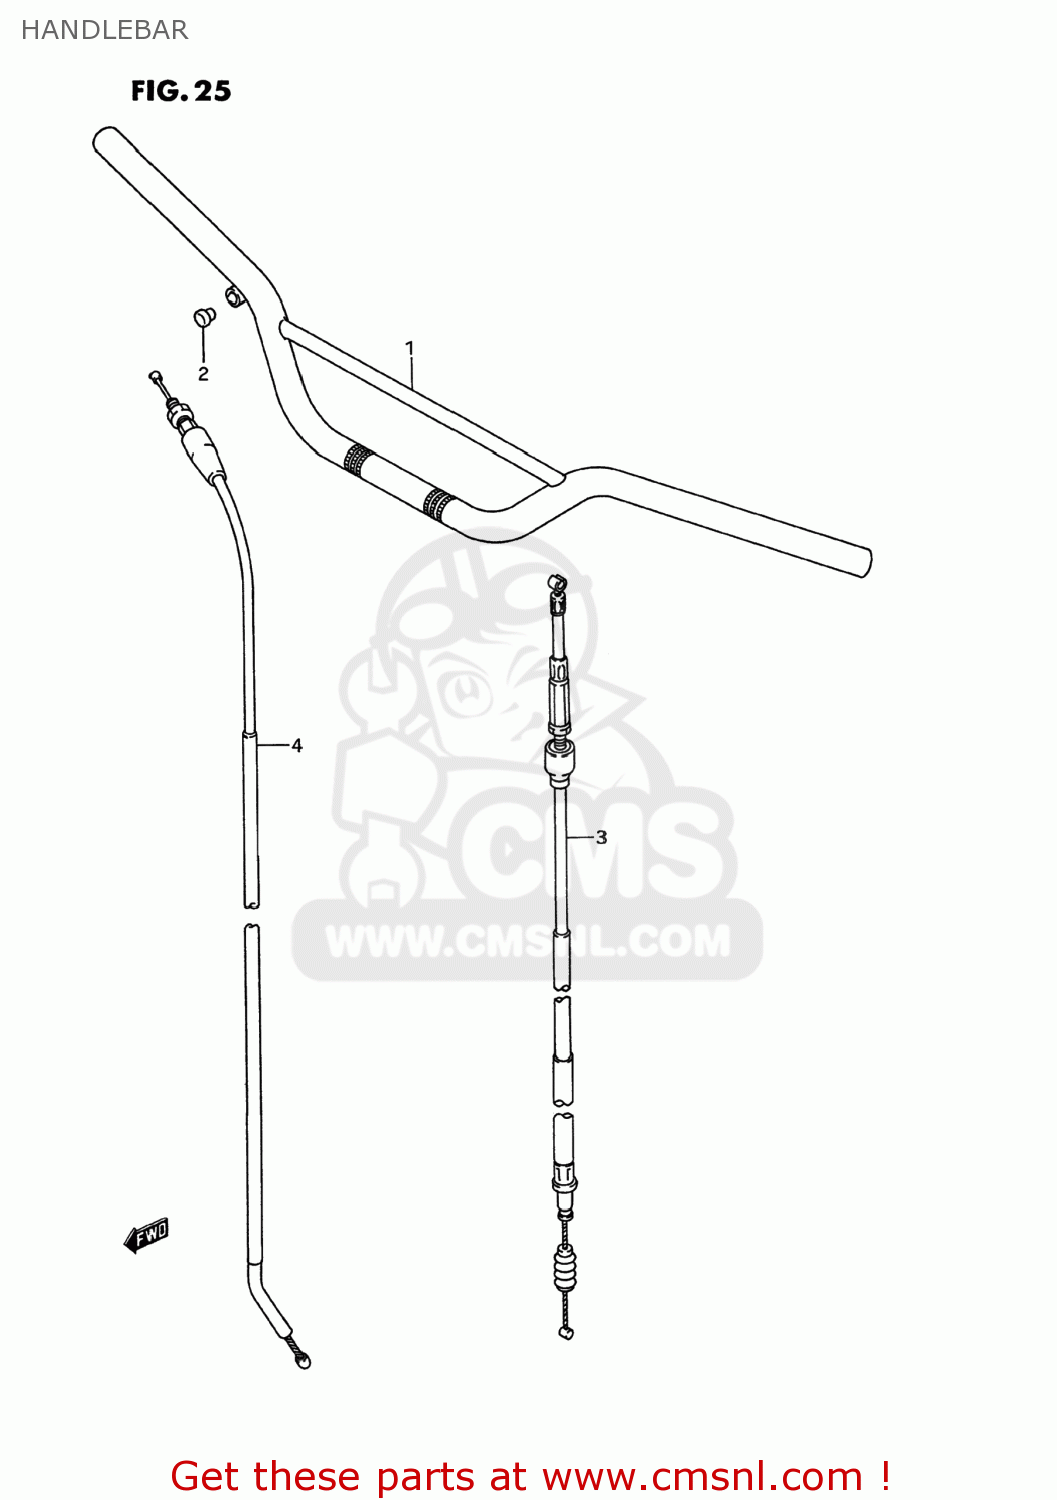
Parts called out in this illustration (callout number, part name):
1	HANDLEBAR
2	CAP(OD:14)
3	CABLE ASSY,CLUTCH
4	CABLE ASSY,THROTTLE
